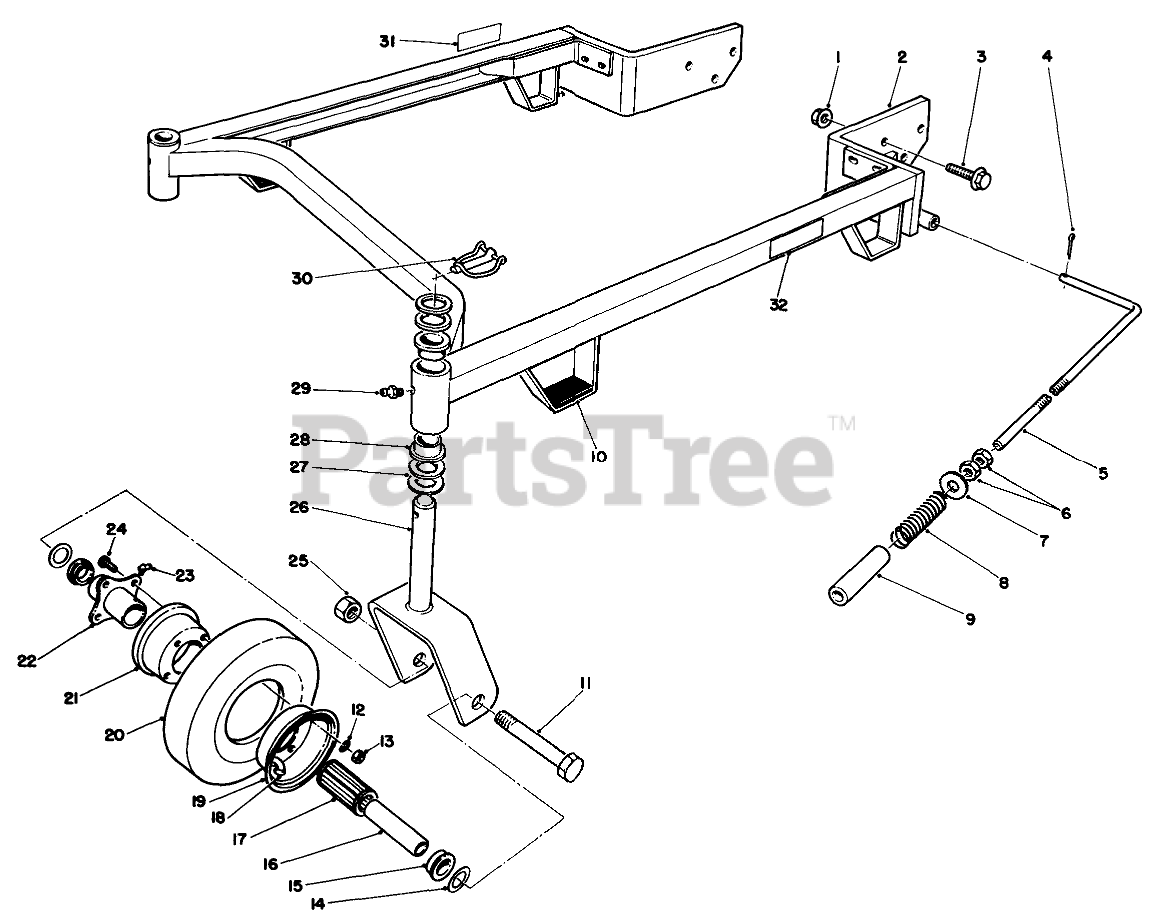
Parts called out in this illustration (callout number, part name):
1	NUT-HF
2	Suspension Frame (Incl. Ref. #28)
3	SCREW-HHF
4	PIN-COTTER
5	ADJUSTING SHAFT
6	NUT-JAM
7	WASHER
8	COMP. SPRING
9	SLEEVE-TUBE, 36 INCH
10	Pad-Rubber
11	SCREW-HH
12	WASHER-LOCK
13	NUT-HEX
14	WASHER-FLAT
15	BEARING-OUTSIDE
16	SPANNER-TIRE
17	BEARING-ROLLER
18	TUBE-INNER (W/VALVE)
19	FEMALE WHEEL HALF
21	MALE WHEEL HALF
22	HUB-CENTER
23	FITTING-GREASE
25	NUT-HEX
26	Castor Fork
27	WASHER-THRUST
28	Bushing
29	FITTING-GREASE
30	PIN-LYNCH
31	DECAL-CAUTION, DEFLECTOR
32	DECAL-HOC, LH
